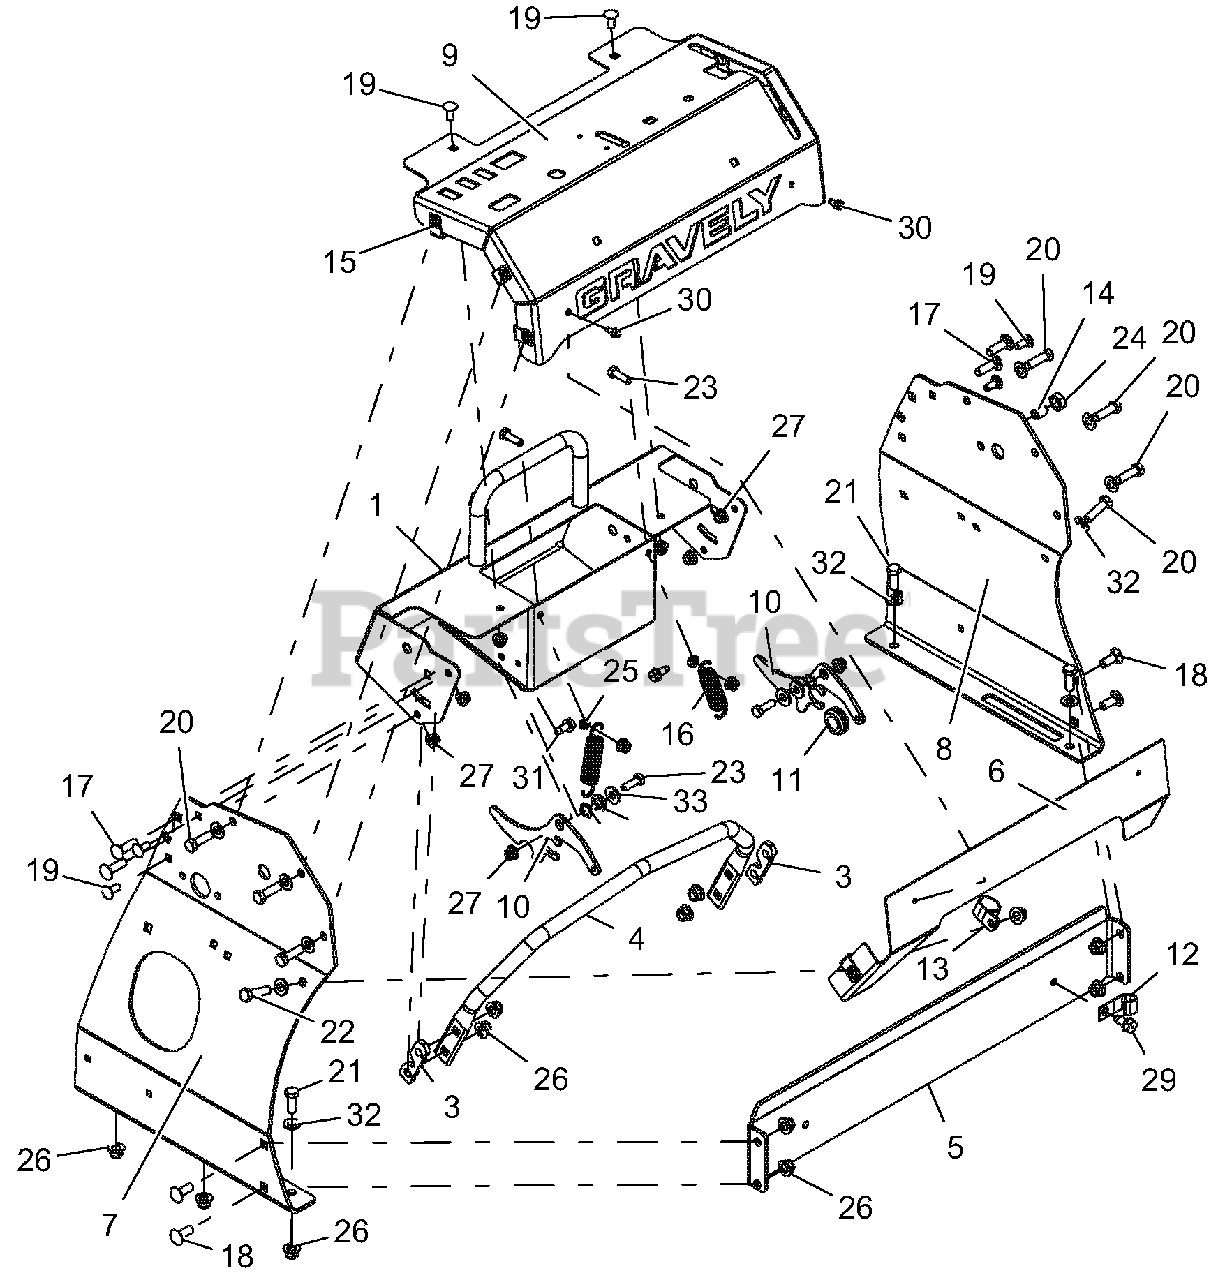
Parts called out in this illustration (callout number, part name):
1	WLDMT, CONTROL PANEL, PRO-STANCE
2	WAVE WASHER .531X.781X.125 FH
3	SHIM, BAR 5 DEG SPEED-BLACK
4	STOP, FORWARD STEERING
5	STIFFENER, TOWER
6	PLATE, FRONT BACKER
7	PANEL, TOWER RH, PRO-STANCE
8	PANEL, PROSTANCE LH TOWER
9	PANEL, CONTROL - PRO-STANCE CARB
10	LATCH, PAD MOUNT
11	GROMMET, SPLIT RUBBER
13	CLAMP, CUSHIONED STEEL REV
14	BALL SPRING PLUNGER, .500-13
15	NUT, RTNR .375-16X.37
16	SPRG, EXTENSION
17	BLT-RDHDSQNK .38-16X1.25 G5 YWZC
18	BLT-RDHDSQNK .38-16X1.00 G5 YWZC
19	BLT-RDHDSQNK .31-18X.75 G5 YWZC
20	BLT-HEX .38-16X1.25 GR5 YWZC
21	BLT-HEX .38-16X1.00 GR5 YWZC
22	BLT-HEX .38-16X1.50 GR5 YWZC
23	BLT-HEX .31-18X1.00 GR5 YWZC
24	NUT, JAM .500-13 YWZC
25	@NUT-LK-CTR-JAM .31-18 YWZC
26	NUT-LK-NYL-FLG .38-16 YWZC
27	NUT-LK-NYL-FLG .31-18 YWZC
28	BSHG, FLG .32X.500.344X.880
29	SCR-TAP .38-16X.75 HWH TR YWZ
30	SCR-TAP .25-20X.50 HWH TR YWZ
31	SCR-TAP .31-18X.75 HWH TR YWZ
32	WSHR-FL-STL.406X.812X.065 YWZ
33	WSHR-FL-STL.38X.875X.083 YWZC
